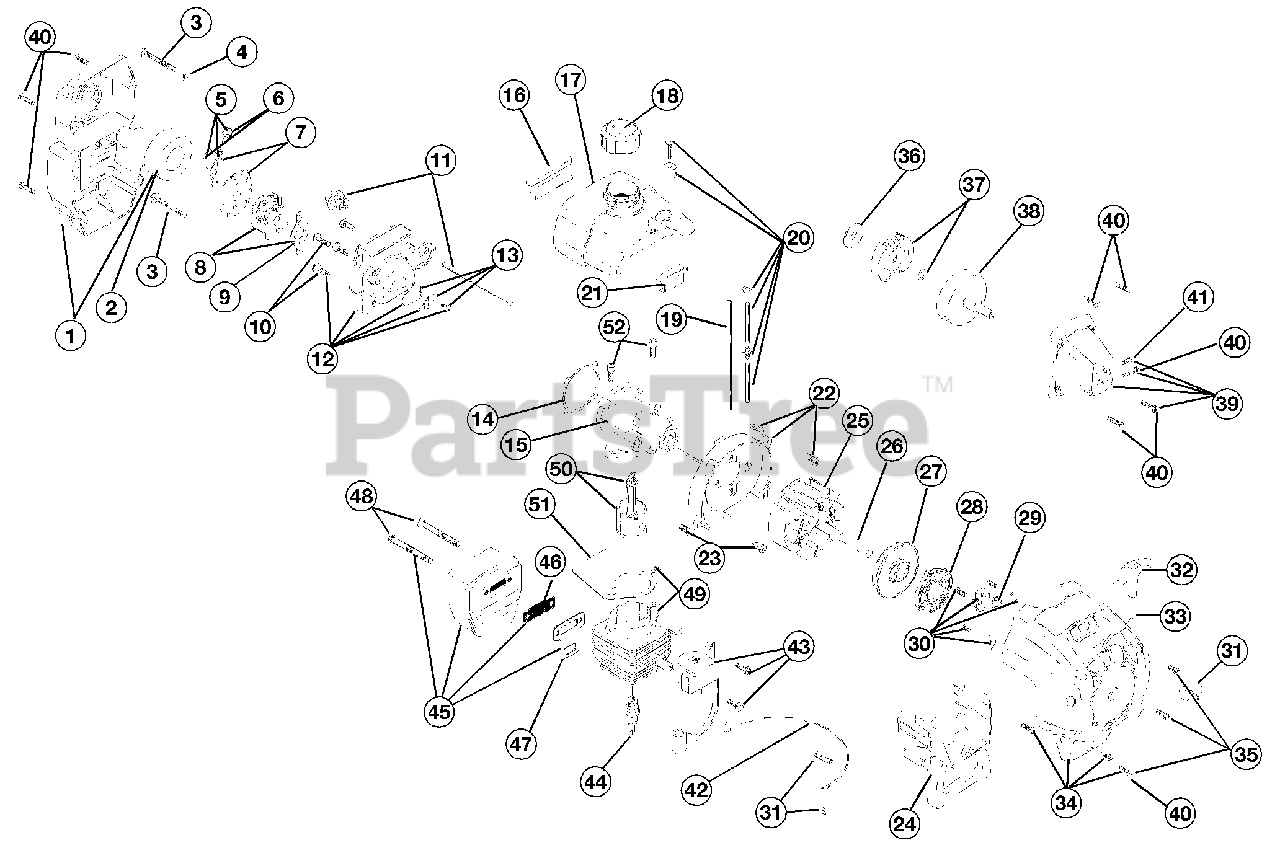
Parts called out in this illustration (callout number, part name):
1	Air Cleaner/Muffler Cover Assembly
2	Air Cleaner Filter
3	Carburetor Mounting Screw Assembly
4	Wavey Washer
5	Choke Lever Assembly
6	Choke Knob and Screw
7	Choke Lever and Plate
8	Carburetor Assembly
9	Carburetor Gasket
10	Carb Mount Screw
11	Primer and Hose Assembly
12	Carb Mount Assembly
13	Reed Assembly
14	Carburetor Mount Gasket
15	Crank Case Service Assembly
16	Rear Mounting Pad
17	Fuel Tank Assembly
18	Fuel Cap Assembly
19	Fuel Return Line
20	Fuel Line Assembly
21	Front Mounting Pad
22	Shroud Assembly
23	Shroud Screw
24	Shroud Extension and Stand
25	Flywheel Assembly
27	Recoil Pulley Assembly
28	Recoil Spring
29	Rope Guide
30	Pulley Retainer Assembly
31	Switch Assembly
32	Pull Handle
34	Starter Housing Assembly
35	Housing Screw
36	Clutch Washer
37	Clutch Rotor Assembly
38	Clutch Drum Assembly
39	Clutch Cover Assembly
41	Anti-Rotation Screw
42	Wire Lead
43	Module Assembly
44	Spark Plug
45	Muffler Assembly
46	Spark Arrestor Screen
47	Exhaust Gasket
48	Muffler Mounting Bolt Assembly
49	Cylinder Assembly
50	Piston and Rod Assembly
51	Cylinder Gasket
52	Cylinder Bolt
